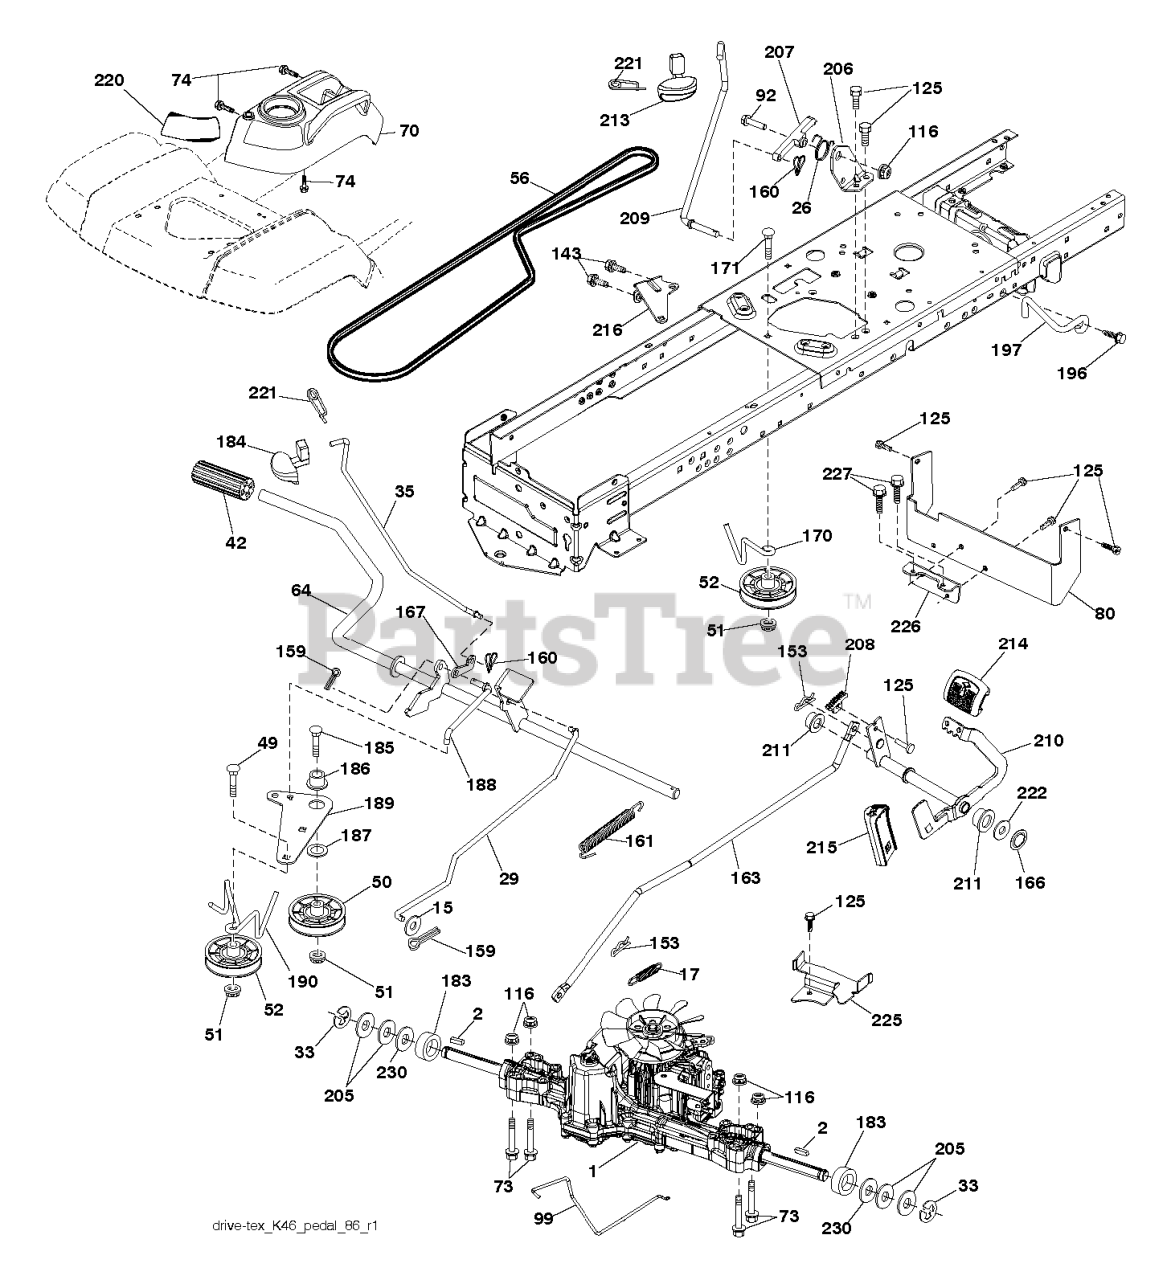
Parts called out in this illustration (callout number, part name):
2	SQUARE KEY
15	WASHER
17	SPRING.BRAKE.K46.GREEN
26	SPRING.RETURN.CRUISE
29	ROD.BRAKE.K46
35	ROD .BRAKE. PARKING. GT. HUSQ.
42	PEDAL COVER T
50	IDLER.FLAT.910.OFFSET
51	NUT LOCK FLG 3/8-16 UNC
52	IDLER.V-GROOVE.910.OFFSET
56	V-BELT.MOWER.92.40.42/K46
64	SHAFT.ASM.PEDAL.BRK.CNTR
70	RP CONSOLE.ASM.PCH.W/TB
73	BOLT
74	SCREW.HI-LO.CONSOLE
80	STRAP TORQUE
92	BOLT
99	ROD.SPRING.BYPASS.K46.LT.Z
116	NUT LOCK HEX FLANGE 5/16-18
125	SCREW
143	Screw 5/16-18 x 1/2 Hex, Self Tapping 5/16-18 x 1/2
153	RETAINER M
159	COTTER PIN
160	RETAINER CLIP
161	SPRING, RETURN LT
163	ROD.CONTROL.K57R.K46
166	NUT.PUSH.625
167	LATCH.BRAKE.SPRING
170	KEEPER.V-IDLER.CENTER.
171	BOLT
183	SPACER AXLE
184	HANDLE.PARKG.BRK.HUSQ X667
186	SPACER.RETAINER
187	WASHER 12/32X2X10GA
188	RP.LINK.CLUTCH.GROUND.DRIVE
189	BELLCRANK.GROUND.DRIVE.TEX.
190	KEEPER.BELLCRANK.DRIVE
196	SCREW 3/8-16X1
197	LINK.CLUTCH.ANIT-ROTAT
206	BRKT.MOUNT.LATCH.CRUIS
207	LATCH.CONTROL.CRUISE
208	GEAR.SECTOR.CONTROL.CR
209	ROD.CONTROL.CRUISE.GT.
210	ROCKER.ASM.PEDAL.CONTR
211	BEARING.NYLON
213	KNOB.CONTROL.CRUSIE.HU
214	PEDAL.FORWARD.PAD.TEX
215	PEDAL.REVERSE.TEX.GT.4
216	BRACKET.PULLEY.IDLER.W/TEX
220	REFLECTOR.RH.TEX GT
221	RETAINER.SPRING.CLIP.H
222	WASHER 21/32 X 1-1/4 X 10 GA.
225	KEEPER.BELT.TRANSAXLE.K46
226	BRACKET.MOUNT.TORQUE.K46.TLT
227	SCREW.THDROL.5/16-18X3/4.TTY
230	WASHER.HARDENED
